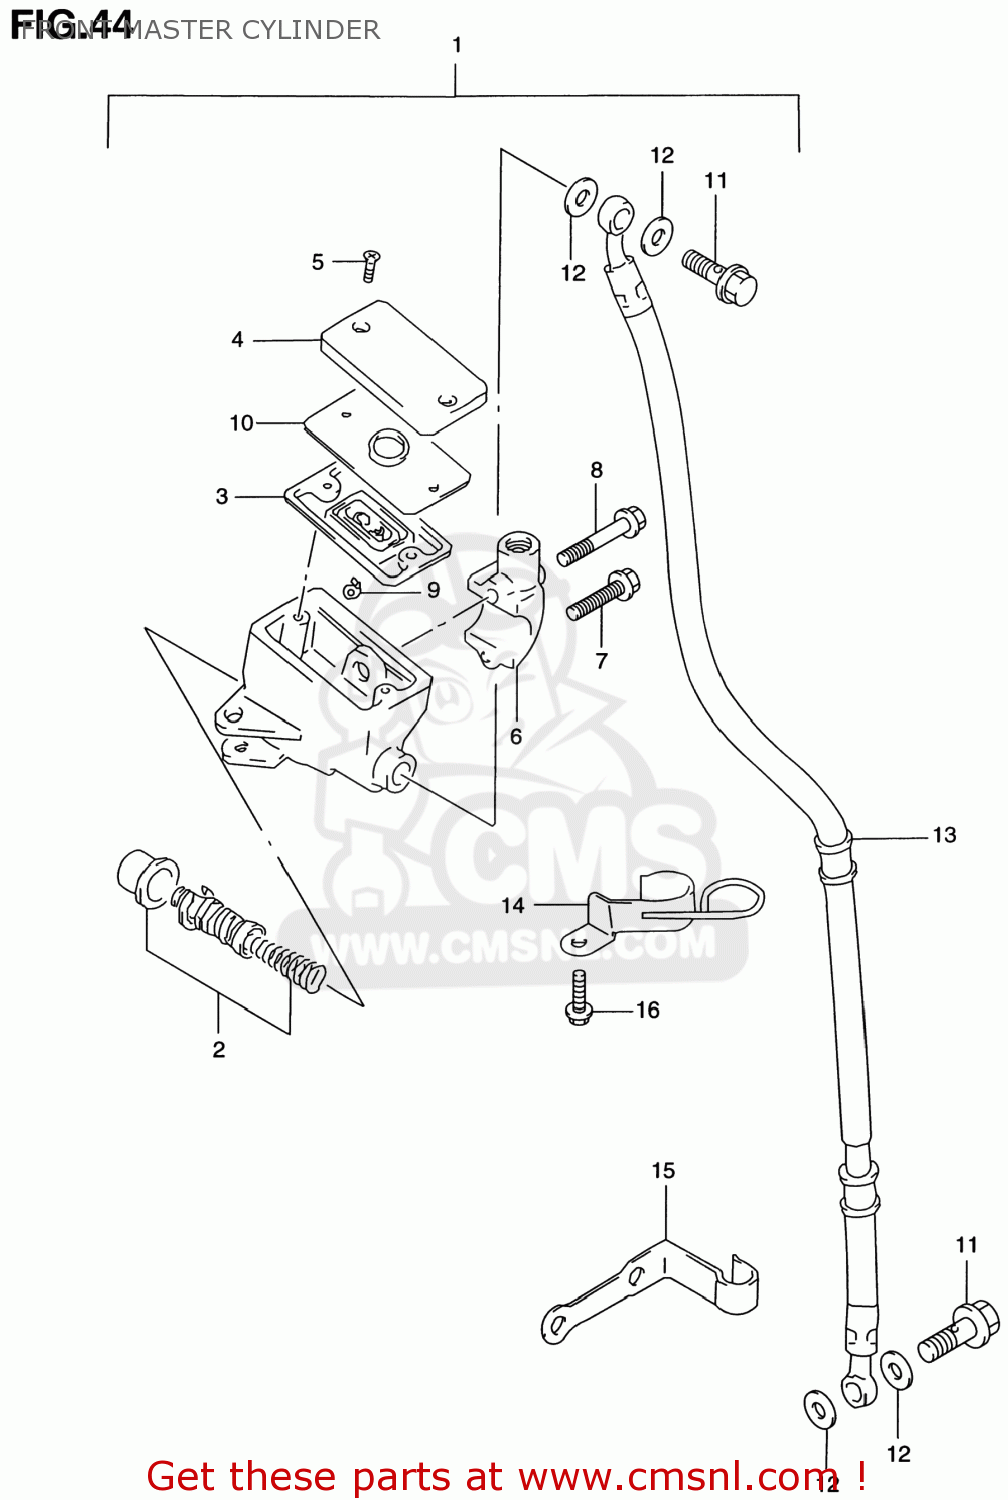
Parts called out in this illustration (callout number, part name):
1	CYLINDER ASSY,FR MASTER
2	PISTON/CUP SET
3	4
4	CAP
5	SCREW
6	HOLDER
7	BOLT(6X25)
8	BOLT(6X38)
9	PROTECTOR
10	PLATE,DIAPHRAGM
11	BOLT UNION
12	WASHER(10X15X1.5)
13	HOSE,FR BRAKE
14	CLAMP,FR BRAKE HOSE
15	CLAMP,BRAKE HOSE
16	BOLT
